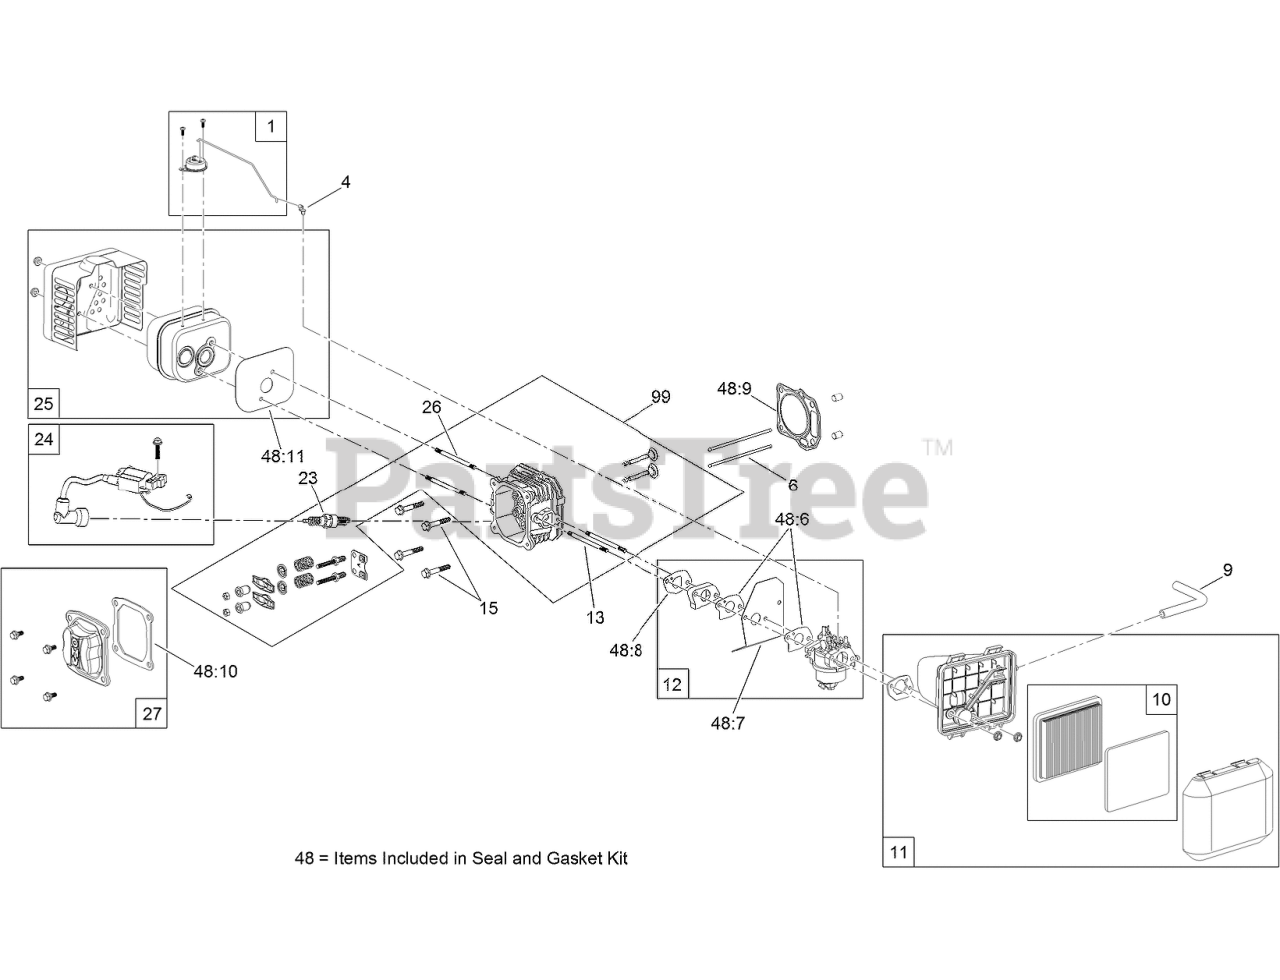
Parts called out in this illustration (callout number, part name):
1	THERMAL CHOKE CONTROL KIT
4	LOCK-THROTTLE
6	ROD-PUSH
9	TUBE-BREATHER
10	AIR FILTER AND PREFILTER KIT
11	AIR CLEANER ASM
12	CARBURETOR REPAIR KIT
12	CARBURETOR COMPLETE KIT
13	STUD-INTAKE
15	BOLT-FLANGE
23	SPARK PLUG
24	IGNITION AND HARDWARE KIT
25	MUFFLER AND SHIELD KIT
26	STUD-EXHAUST
27	VALVE COVER KIT
48	SEAL AND GASKET KIT
48:6	GASKET-CARBURETOR
48:7	INSULATOR-CARBURETOR
48:8	GASKET-CARBURETOR
48:9	GASKET-HEAD
48:10	GASKET-VALVE COVER
48:11	GASKET-EXHAUST
99	HEAD ASM
